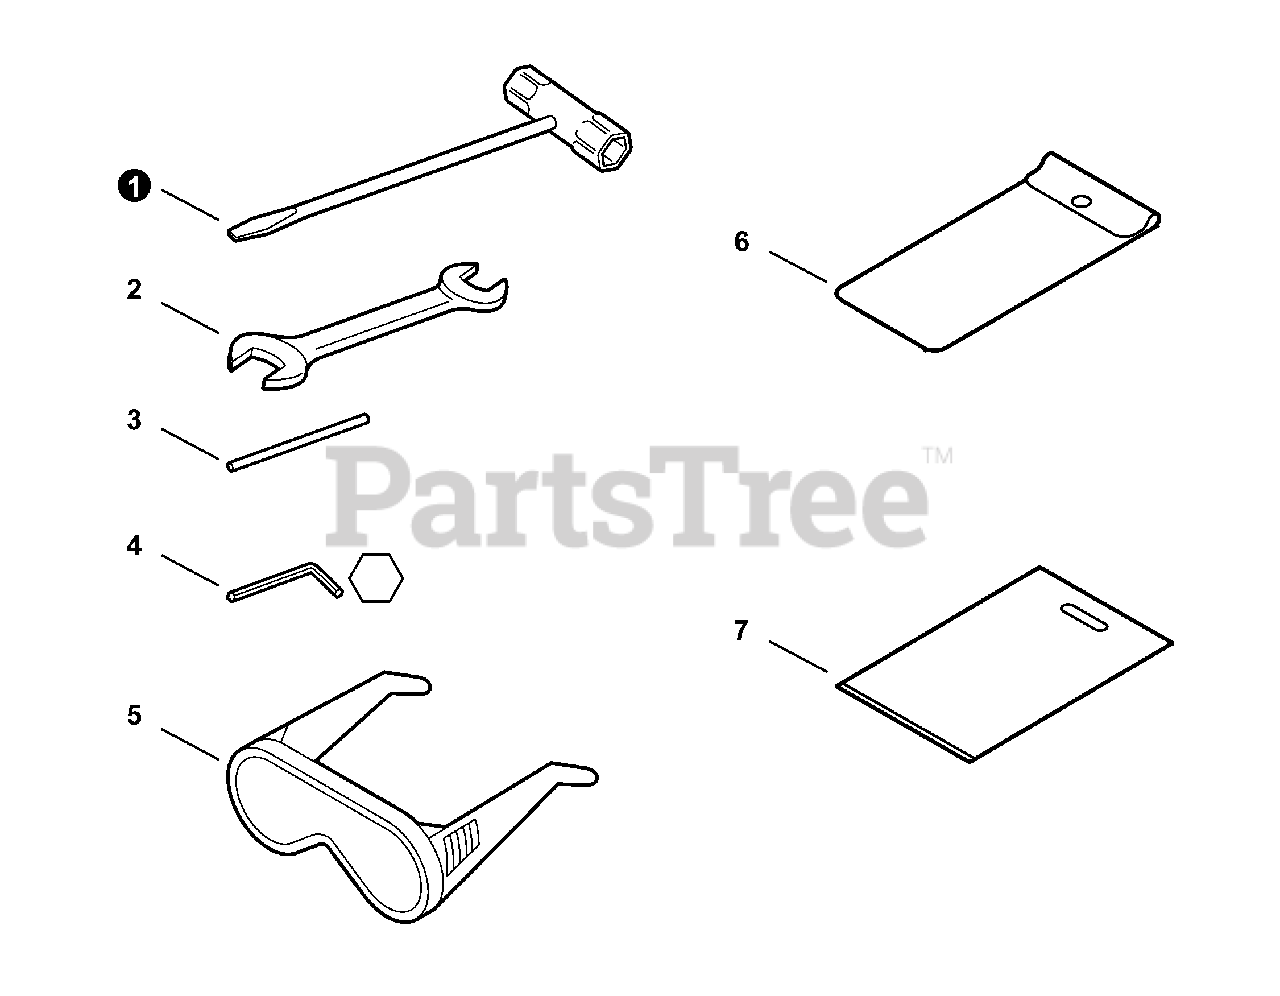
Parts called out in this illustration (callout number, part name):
1	T-WRENCH 17×19 L200
2	SPANNER 8×10
3	TOOL, LOCKING 5×120 MM
4	WRENCH, ALLEN 4 MM
5	GLASSES, SAFETY
6	BAG, TOOL
7	CASE, TOOL
